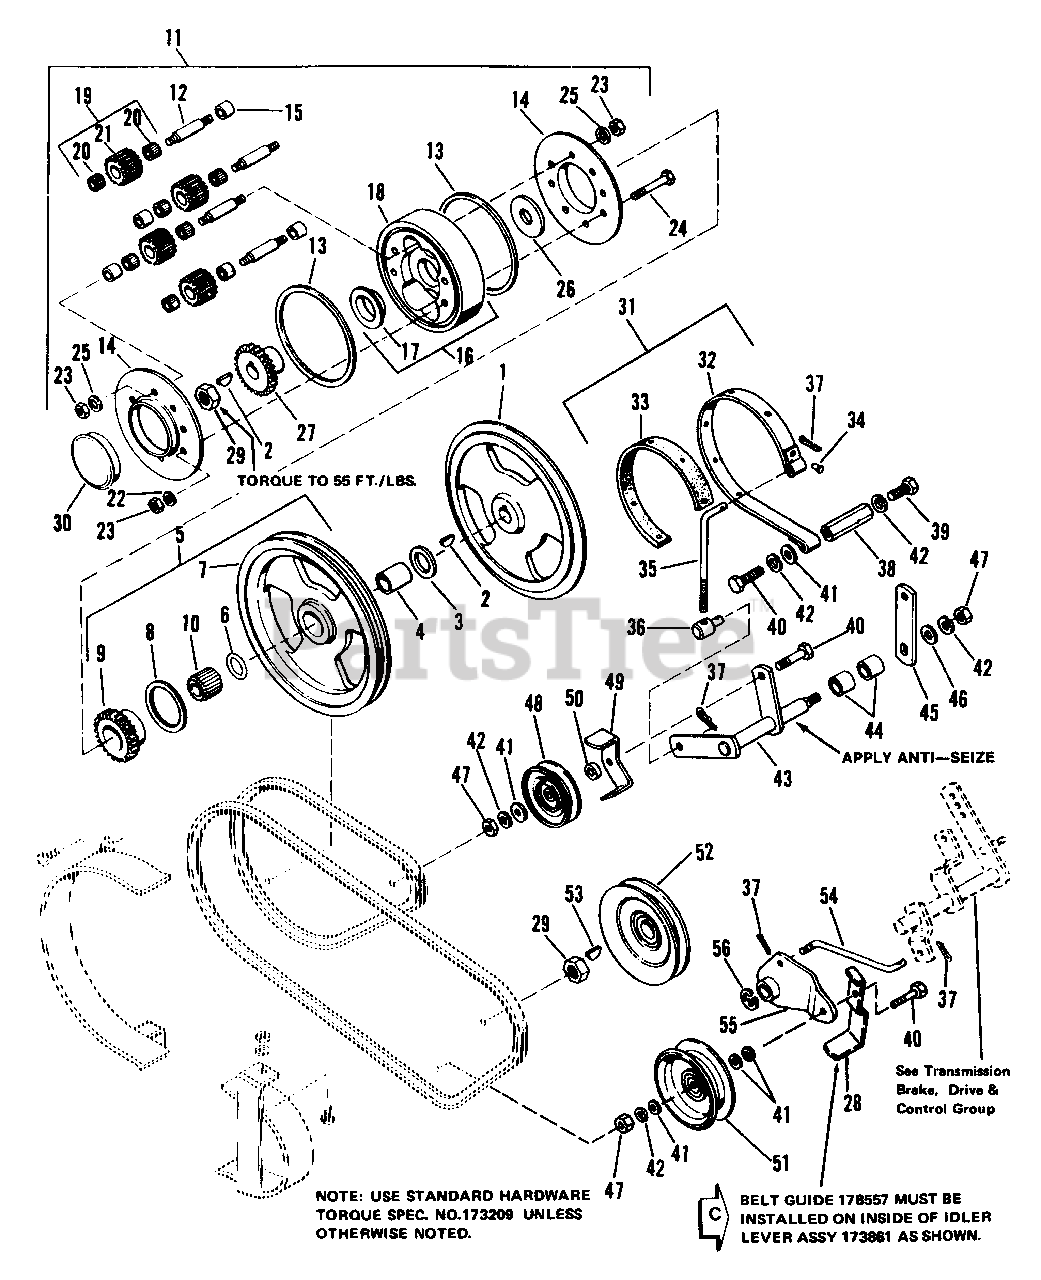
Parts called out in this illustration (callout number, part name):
1	PULLEY, Half
2	KEY, Woodruff, No. 9
3	BEARING, Thrust
4	RACE, Inner
5	PULLEY ASSY
9	GEAR, Sun
10	BEARING, Needle
11	* PLANETARY ASSY
12	PIN, Pinion
14	COVER, Differential
15	BEARING, Sleave
16	CARRIER SUB-ASSY, Planetary
17	BEARING, Flange
18	CARRIER, Planetary
19	PINION ASSY, Planetary
20	BEARING, Needle
21	PINION, Planetary
22	LOCKWASHER, 5/16
23	NUT, Hex, Full, 5/16-18
24	CAPSCREW, Hex Hd., 5/16-18 x 2
25	LOCKWASHER, Internal, 5/16
26	WASHER, Thrust
27	GEAR, Sun
28	GUIDE, Belt
29	NUT, Hex, Jam, Lock, 3/4-16
31	BRAKE BAND ASSY
32	BAND, Brake
34	RIVET, No. 7 x 1/4
37	PIN, Cotter, 3/32 x 3/4
38	ANCHOR, Brake
39	CAPSCREW, Hex Hd., 3/8-16 x 1
40	CAPSCREW, Hex Hd., 3/8-16 x 1-1/2
41	WASHER, 5/16
42	LOCKWASHER, 3/8
43	LEVER ASSY
46	WASHER, 3/8
47	NUT, Hex, Full, 3/8-16
48	PULLEY, Idler
49	GUIDE, Belt
51	PULLEY, Idler
52	PULLEY, Drive
54	LINK, Clutch
55	LEVER ASSY, Idler
56	"E" RING
